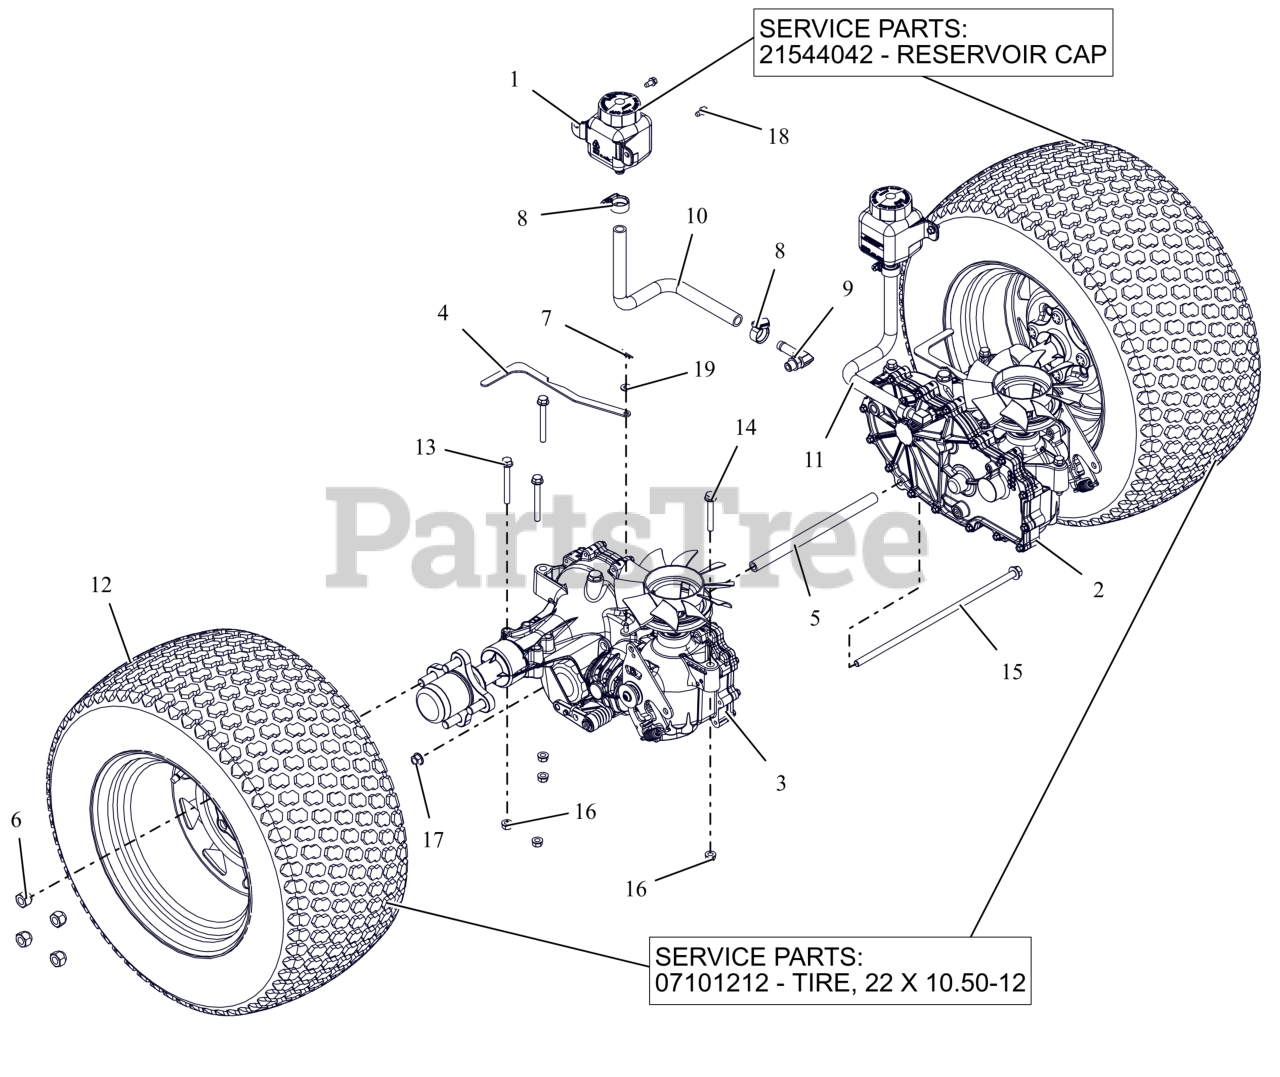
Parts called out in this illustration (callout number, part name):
1	TANK, EXPANSION
1	CAP, HYDRO RESERVOIR REPLAC.
2	TRANSAXLE, ZT3100 LH
3	TRANSAXLE, ZT3100 RH
4	BRKT, VALVE DUMP
5	SPCR,TRANS. .406IDX.63ODX9.95L
6	NUT, WHEEL .50-20 ZCC
7	PIN, HAIR #225 .072X1.09
8	CLAMP,.88 DIA. HOSE
9	FITTING, HYD (90 DEG)
10	HOSE, FORMED EXPANSION -HD RH
11	HOSE, FORMED EXPANSION -HD LH
12	ASM, WHL/TIRE 22X10.50-12 K500
12	TIRE, 22X10.50-12
13	BLT,HEX-FLG .31-18X2.75 G5 ZCC
14	BLT,HEX-FLG .31-18X2.25 G5 ZCC
15	BLT,HEX-FLG .38-16X13 G5 ZCC
16	NUT,LK-CTR-FLG .31-18 GF ZCC
17	NUT-LK-CTR-FLG .375-16 GF ZCC
18	SCR-TAP .25-20X.50 HWH ZCC
19	WSHR,FLT .281X.625X.065 ZCC
